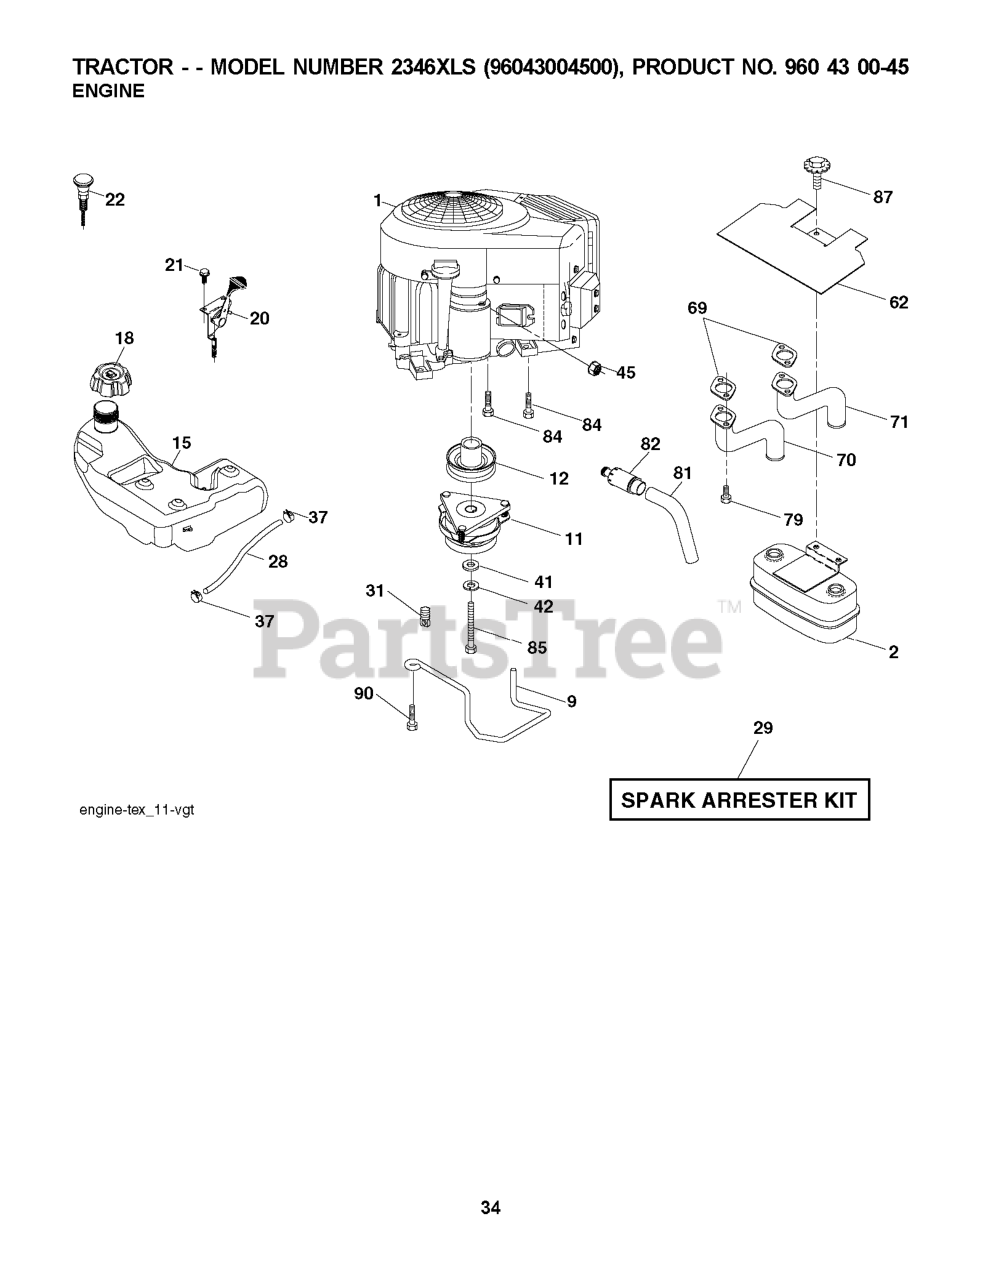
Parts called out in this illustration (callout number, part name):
2	MUFFLER.TWIN.CYL.LOW.TONE
9	KEEPER.BELT.ENGINE.4.2
11	CLUTCH.ELECTRIC.LT.48"*
12	PULLEY.ENGINE.TUFFTORQ
15	TANK.FUEL.4GAL
18	CAP.FUEL.TANK.3"GREY
20	THROTTLE CABLE
21	SCREW.#10 X 0.750.BOS
22	CONTROL.CHOKE.ERGO.PUSH-IN.BLA
28	LINE.FUEL.64"REAR.EMIS
29	KIT.SPARK ARRESTOR 794945 B&S
37	HOSE CLAMP
42	LOCKWASHER
45	NUT
62	RP SHIELD HEAT MUFFLER
69	GASKET.MUFF 806237 NOW 806425
70	EXHAUST.TUBE.MUFFLR.LH.VANG
71	EXHAUST.TUBE.MUFFLR.RH.VANG
79	SCREW.TUBE.MUFFLER.VANGUARD
81	TUBE, DRAIN OIL ASM.
82	PLUG DRAIN OIL EASY
84	SCREW.3/8-16
85	BOLT HEX 7/16-20X4-1/4"
87	BOLT.5/16-18UNCX3/4 W/SEMS.BLK
90	SCREW 3/8-16X1
